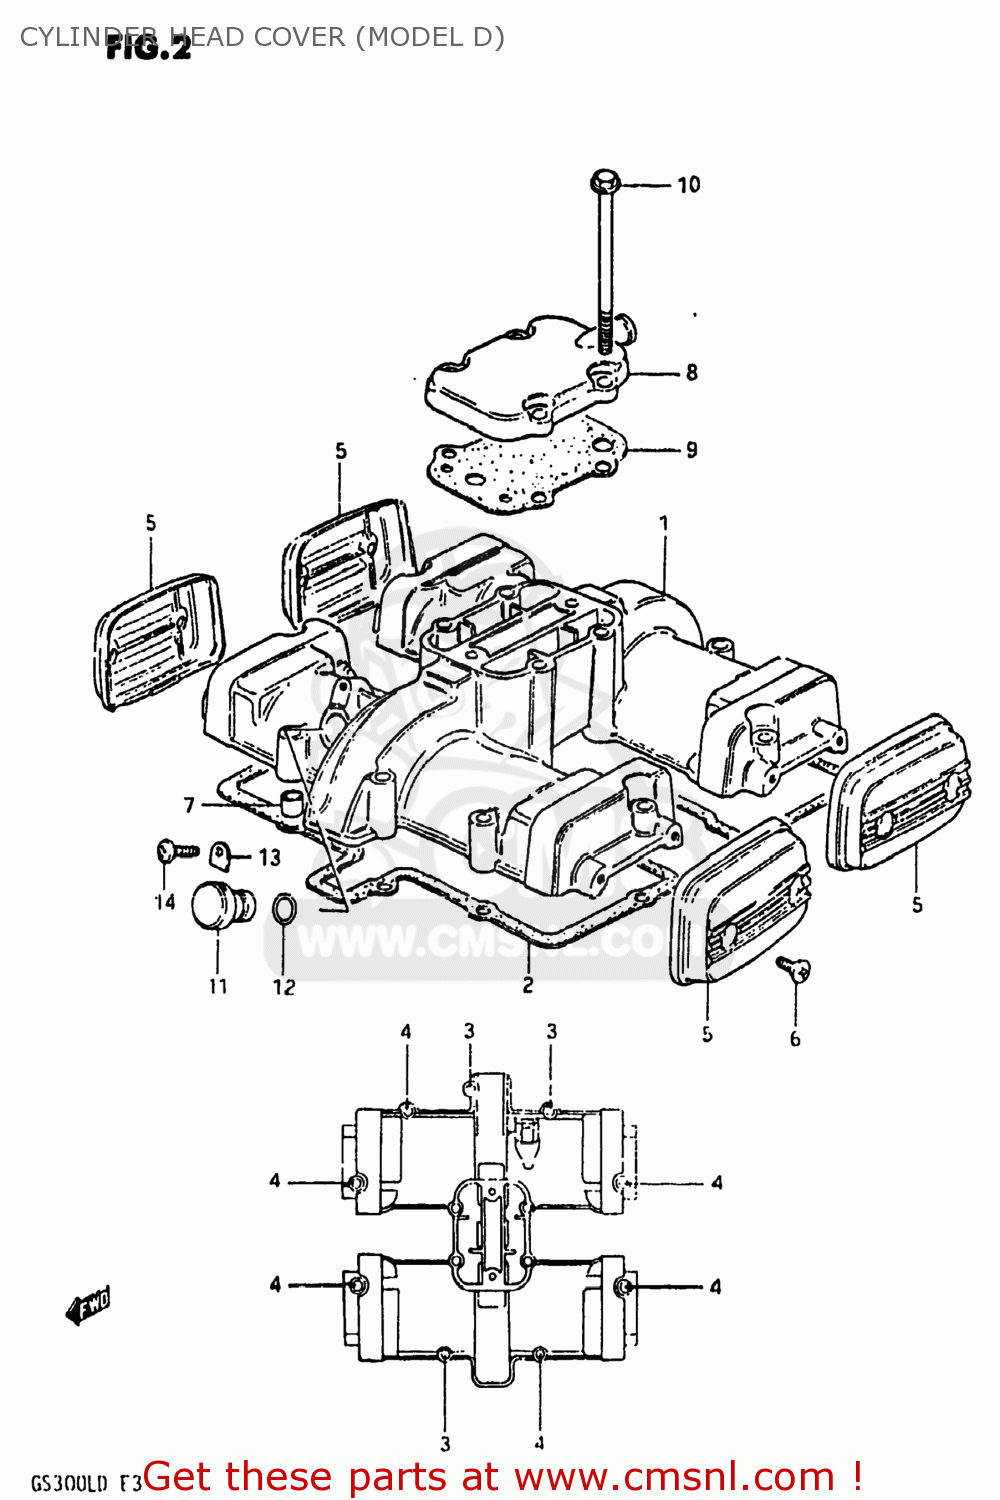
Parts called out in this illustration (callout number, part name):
1	COVER,CYLINDER HEAD
2	GASKET,CYLINDER HEAD COVER (MCA)
3	BOLT (6X40)
4	BOLT
5	CAP,CYLINDER HEAD COVER
6	SCREW(5X12)
7	PIN(6.2X8X11)
8	COVER,BREATHER
9	GASKET,BREATHER COVER (MCA)
10	BOLT (6X75)
11	PLUG,TACH GEAR SLEEVE HOLE
12	SEAL,TACHOMETER DRIVEN
13	PLATE,TACH DRIVE GEAR SLEEVE
14	SCREW(5X12)
